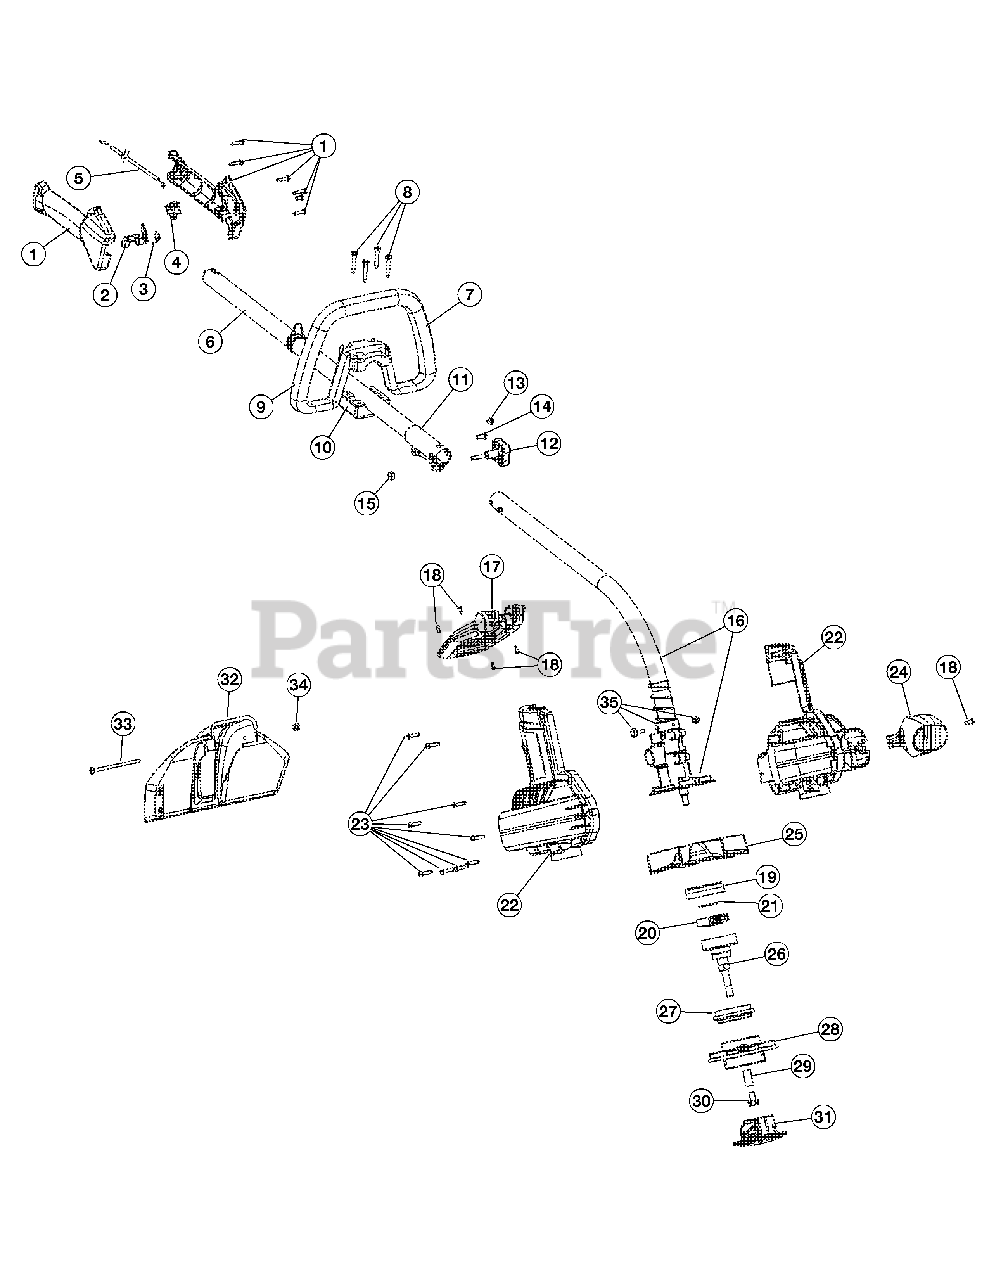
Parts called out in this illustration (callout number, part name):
1	Throttle Housing Assembly (includes 2-4)
2	Throttle Trigger
3	Throttle Trigger Spring
4	Switch Assembly
5	Throttle Cable (marked 746-04234)
6	Upper Drive Shaft Housing Assembly
7	Deluxe D-Handle Assembly (includes 8-10)
9	D-Handle
10	D-Handle Base
11	Split Boom Coupler (includes 12-15)
12	Adjustment Knob (includes 15)
15	Nut
16	Lower Drive Shaft Housing Assembly
17	Handle Shift Assembly (includes 18)
18	Screw
19	Clutch Drum Container
20	Clutch Assembly
21	Washer
22	Housing Assembly (includes 23)
23	Screw
24	Nozzle
25	Impeller
26	Clutch Drum Assembly w/Spool Shaft
27	Adapter
28	Cutting Head Assembly
29	Spacer
30	Bolt
31	Cap
32	Guard Assembly w/Blade (includes 33 & 34)
33	Screw
34	Nut
35	Clamp Assembly
